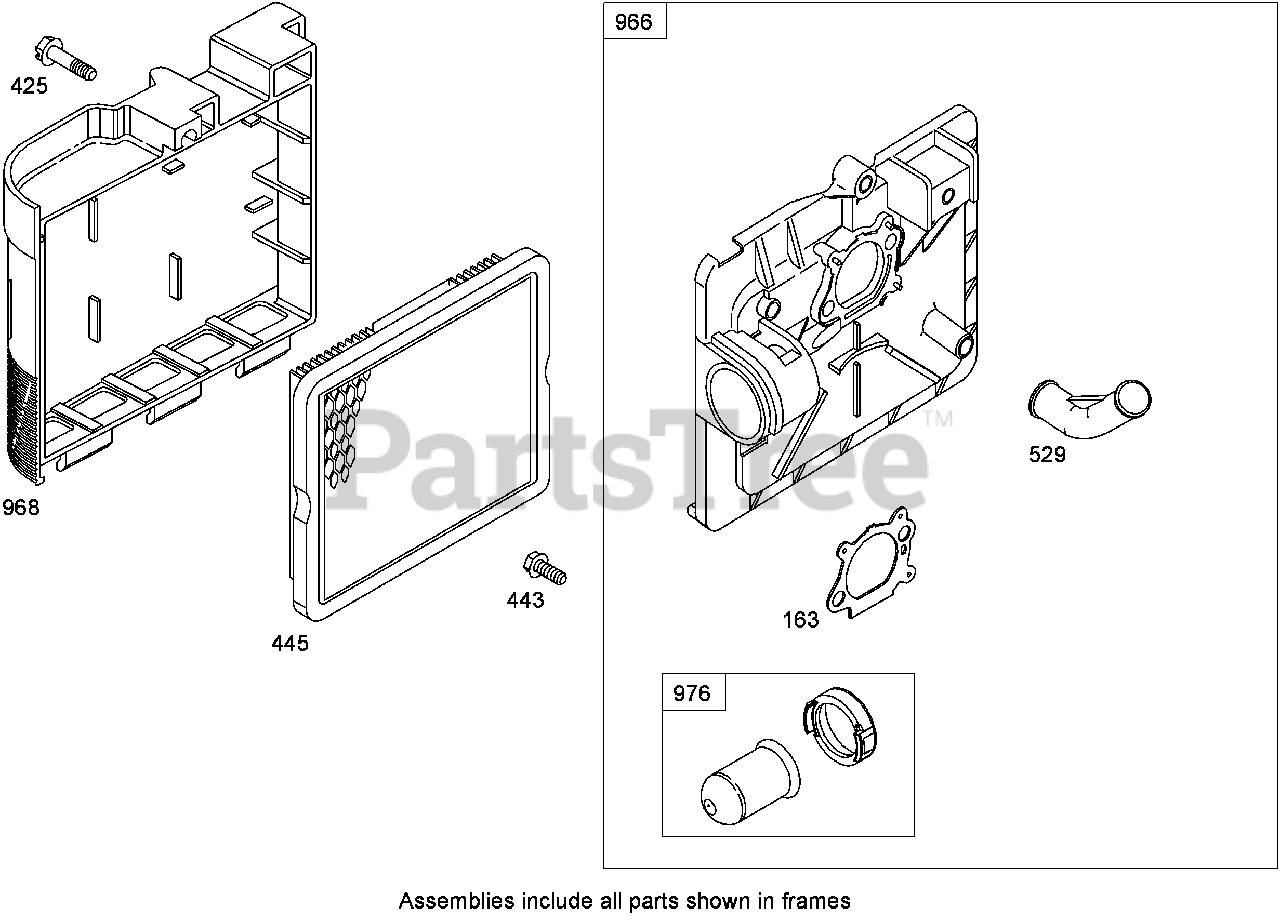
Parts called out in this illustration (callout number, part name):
163	Gasket-Cleaner, Air
425	Screw (Air Cleaner Cover)
443	Screw (Air Cleaner Primer Base)
445	Filter-Cartridge, Air Cleaner
529	Grommet
966	Base-Primer, Air Cleaner
968	Cover-Cleaner, Air
976	Primer-Carburetor
